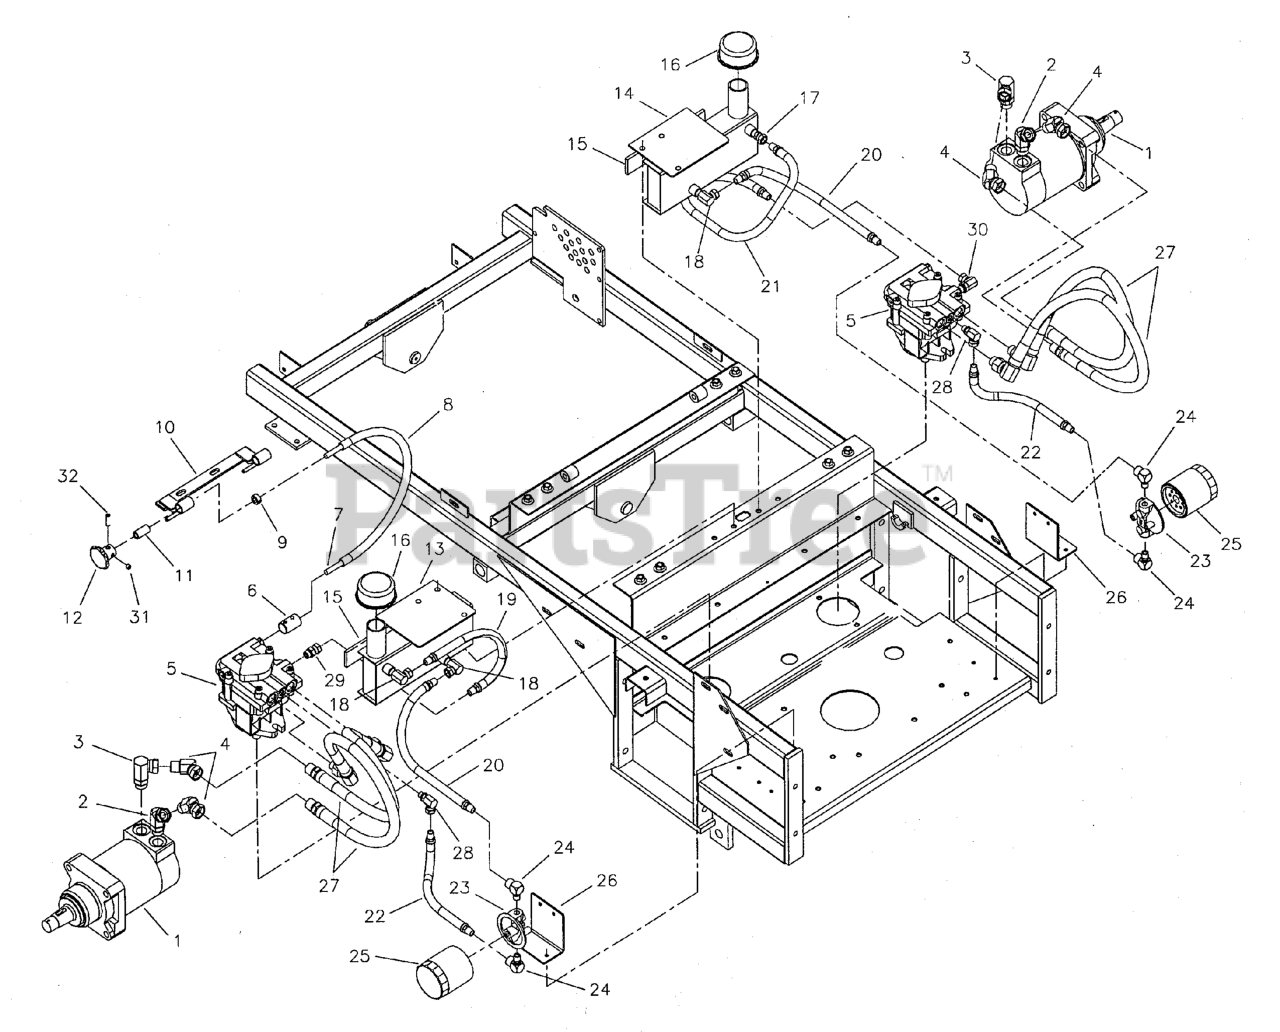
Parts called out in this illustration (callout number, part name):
1	HYDRAULIC WHEEL MOTOR
2	FITTING, 7/8" O-Ring 45 Degree Swivel
3	FITTING, O-Ring, 90 Deg. Swivel
4	FITTING, 1/2 NPT, 45 Deg. Swivel
5	HYDRAULIC PUMP
6	COLLAR, Dump Valve
7	SHAFT, 3/8" Flexible
8	HOUSING, Flex Shaft
9	COLLAR, 3/8" Set
10	BUSHING, Brass
11	KNOB, Dump Valve
12	KNOB, Dump Valve
13	HYDRO TANK, LH
14	HYDRO TANK, RH
15	RUBBER PAD
16	BREATHER
17	FITTING, 1/4" NPT Straight Swivel
18	FITTING, 1/4" NPT 90 Degree Swivel
19	HYDRO HOSE ASSEMBLY, 14"
20	HYDRO HOSE ASSEMBLY, 13"
21	HYDRO HOSE ASSEMBLY, 24"
22	HYDRO HOSE ASSEMBLY, 11"
23	FILTER HEAD
24	FITTING, 1/4 NPT, 90 Deg.
25	FILTER
26	MOUNT, Filter head
28	FITTING, 7/16" O-Ring 90 Degree Swivel
29	FITTING, 9/16" O-Ring Straight Swivel
30	FITTING, 9/16 O-RING - 1/4 NPT, 90 DEG
31	SET SCREW, 5/16" x 1/4" w/Patch
32	SET SCREW, 5/16-18 x 1"
